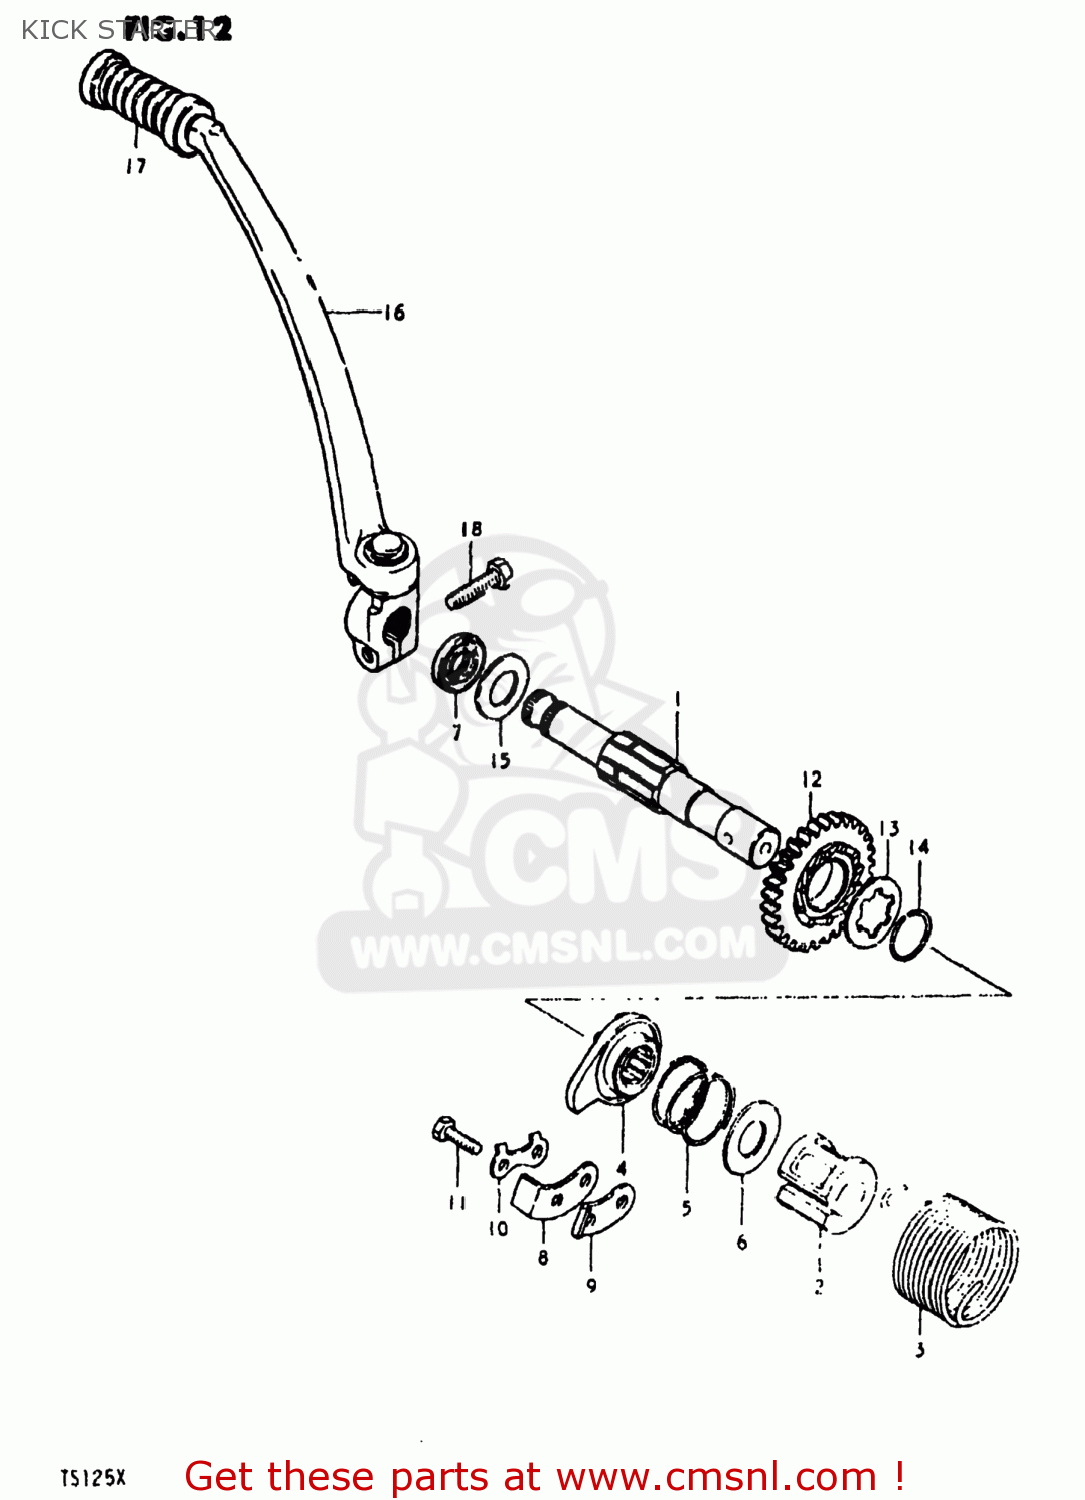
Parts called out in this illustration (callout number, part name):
1	SHAFT,KICK STARTER
2	GUIDE,KICK STARTER SFT SPRING
3	SPRING
4	STARTER,KICK
5	SPRING
6	WASHER
7	SEAL,OIL(16X30X8)
8	GUIDE,KICK STARTER
9	STOPPER,KICK STARTER
10	WASHER
11	BOLT, UPPER
12	GEAR,KICK STARTER DRIVE
13	WASHER,LOCK
14	CIRCLIP
15	WASHER(16X30X1)
16	LEVER ASSEMBLY,KICK STARTER
17	RUBBER,KICK STARTER PEDAL
18	BOLT
